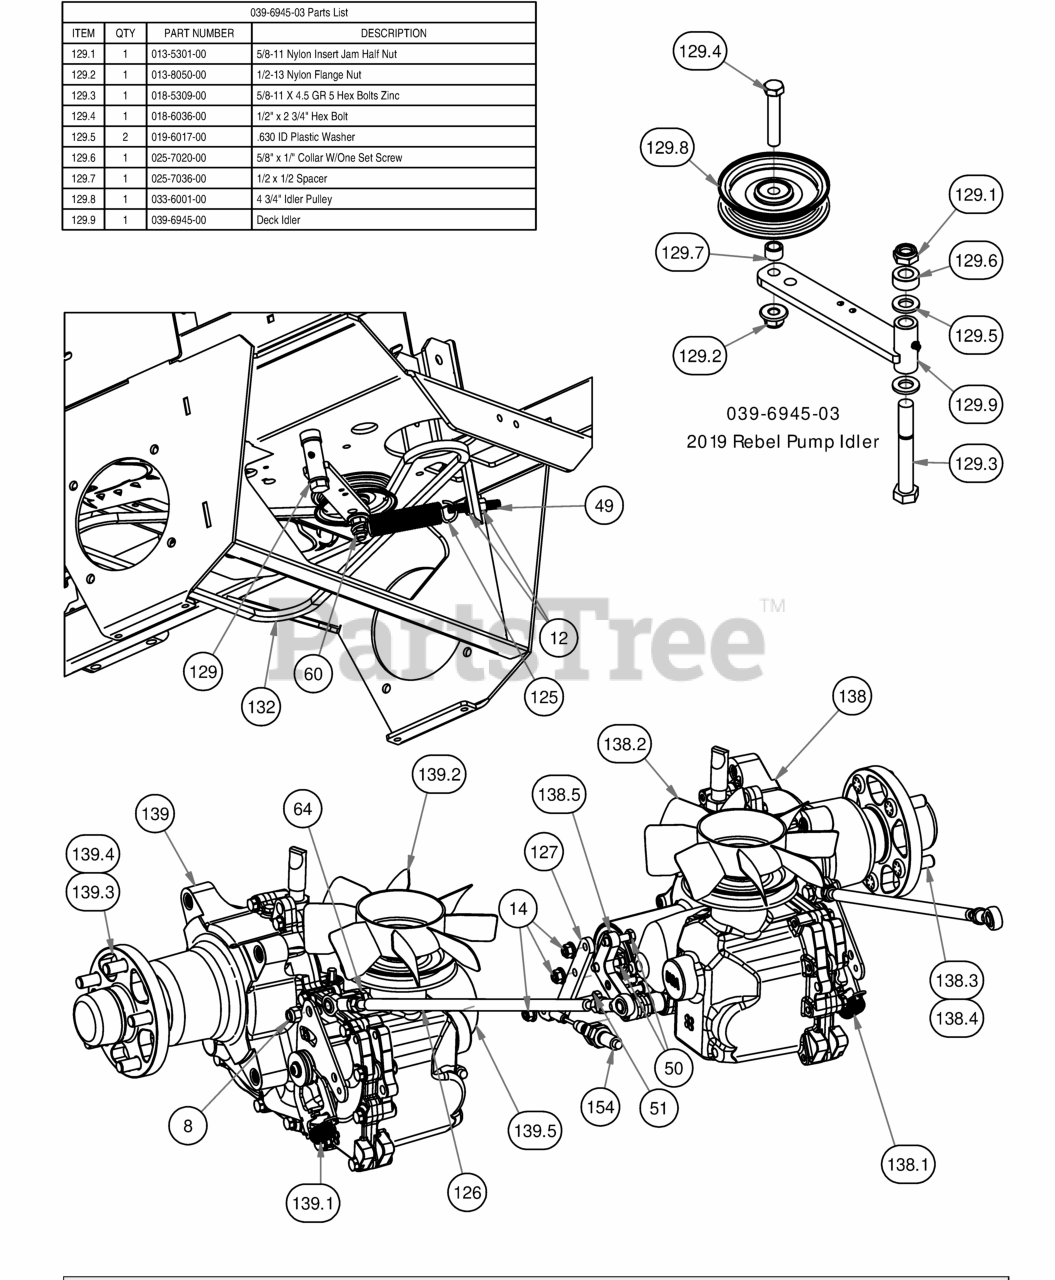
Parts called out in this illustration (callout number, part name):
8	3/8 Nylock Nut
12	1/2" Hex Nut
14	5/16" Nylon Flange Nut
49	All Thread-Pump Idler Tensioner
50	5/16 x 1 1/4 Hex Bolt
51	5/16" x 1" Bolt
60	1/2" Nylcock Nut (1/2 Jam)
64	3/8" x 1 1/4" Hex Bolt
125	Deck spring big diameter
126	2019 Outlaw Rigid Push Rod Assembly
127	2015 Outlaw Brake Adapter (4400 Transaxles Only)
129	2019 Rebel Pump Idler
129.1	5/8-11 Nylon Insert Jam Half Nut
129.2	1/2-13 Nylon Flange Nut
129.3	5/8-11 X 4.5 GR 5 Hex Bolts Zinc
129.4	1/2" x 2 3/4" Hex Bolt
129.5	.630 ID Plastic Washer
129.6	5/8" x 1/" Collar W/One Set Screw
129.7	1/2 x 1/2 Spacer
129.8	4 3/4" Idler Pulley
129.9	Deck Idler
132	2019 Rebel Pump Belt
138	4400 Transaxle - Left Hand
138.1	Transaxle Spring
138.2	Fan/Pulley Kit for 4400 Transaxle
138.3	Hub/Stud Kit for 4400 Transaxle
138.4	Seal Kit for 4400 Transaxle
138.5	Hydro Filter for 4400 Transaxle
139	4400 Transaxle - Right Hand
139.1	Transaxle Spring
139.2	Fan/Pulley Kit for 4400 Transaxle
139.3	Hub/Stud Kit for 4400 Transaxle
139.4	Seal Kit for 4400 Transaxle
139.5	Hydro Filter for 4400 Transaxle
154	Long Brake Cable
